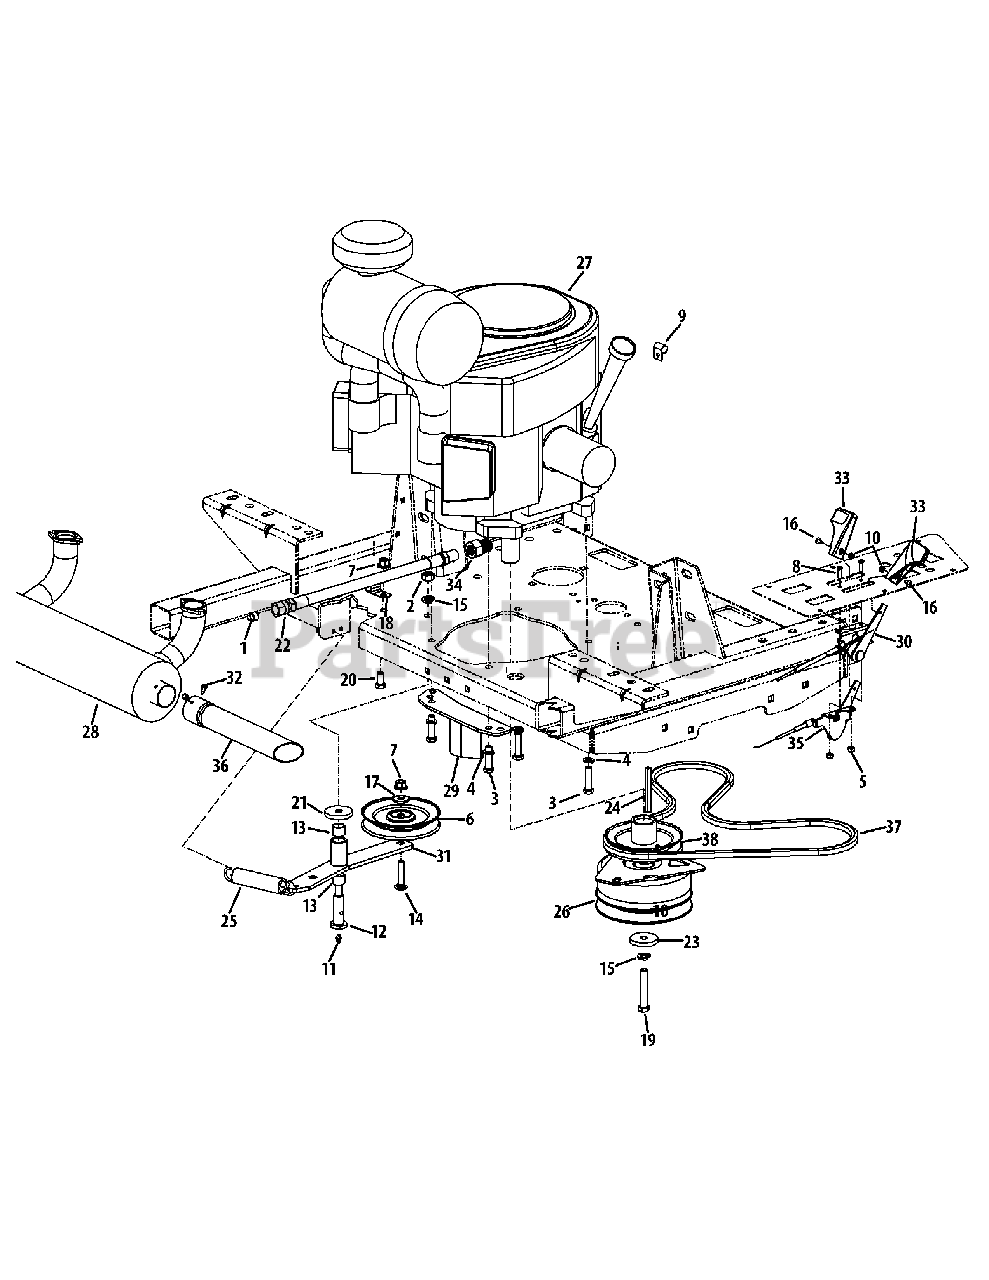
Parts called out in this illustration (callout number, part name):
1	Pipe Plug, 3/8
2	Nut, 7/16-14
3	Hex Screw, 3/8-16 x 1.50
4	Lock Washer, .375 x .680 x .100
5	Nut, #10-32
7	Flange Counter Lock Nut, 3/8-16
8	Machine Screw, #10-32 x .625
9	Clamp, 1/2
10	Nut, #8-32
11	Grease Fitting, 1/4-28
12	Shoulder Bolt, .625 x 1.95
13	Sleeve Bearing, .628 x .753 x .625
14	Carriage Bolt, 3/8-18 x 1.75
15	Lock Washer, .490 x .776 x .114
16	Machine Screw, #8-32 x .356
17	Washer, .406 x 1.00 x .105
18	Clip, .470 x 1.80
19	Hex Screw, 7/16-20 x 2.50
20	Hex Screw, 3/8-16 x .750
21	Washer, .438 x 1.75 x .250
22	Oil Drain Hose
23	Washer, .438 x 1.745 x .250
24	Key, .250 x .250 x 3.00
25	Extension Spring, .98 x 5.0 x .140
26	Brake Clutch
27	Kawasaki FX1000-S09 Engine
29	Clutch Return Assembly
30	Choke Cable
31	Idler Arm Assembly
32	Hex Washer Screw, #10-16 x 0.500
33	Throttle Control Knob
34	Fitting, 1.0
35	Throttle Cable
36	Exhaust Pipe
38	Drive Pulley
